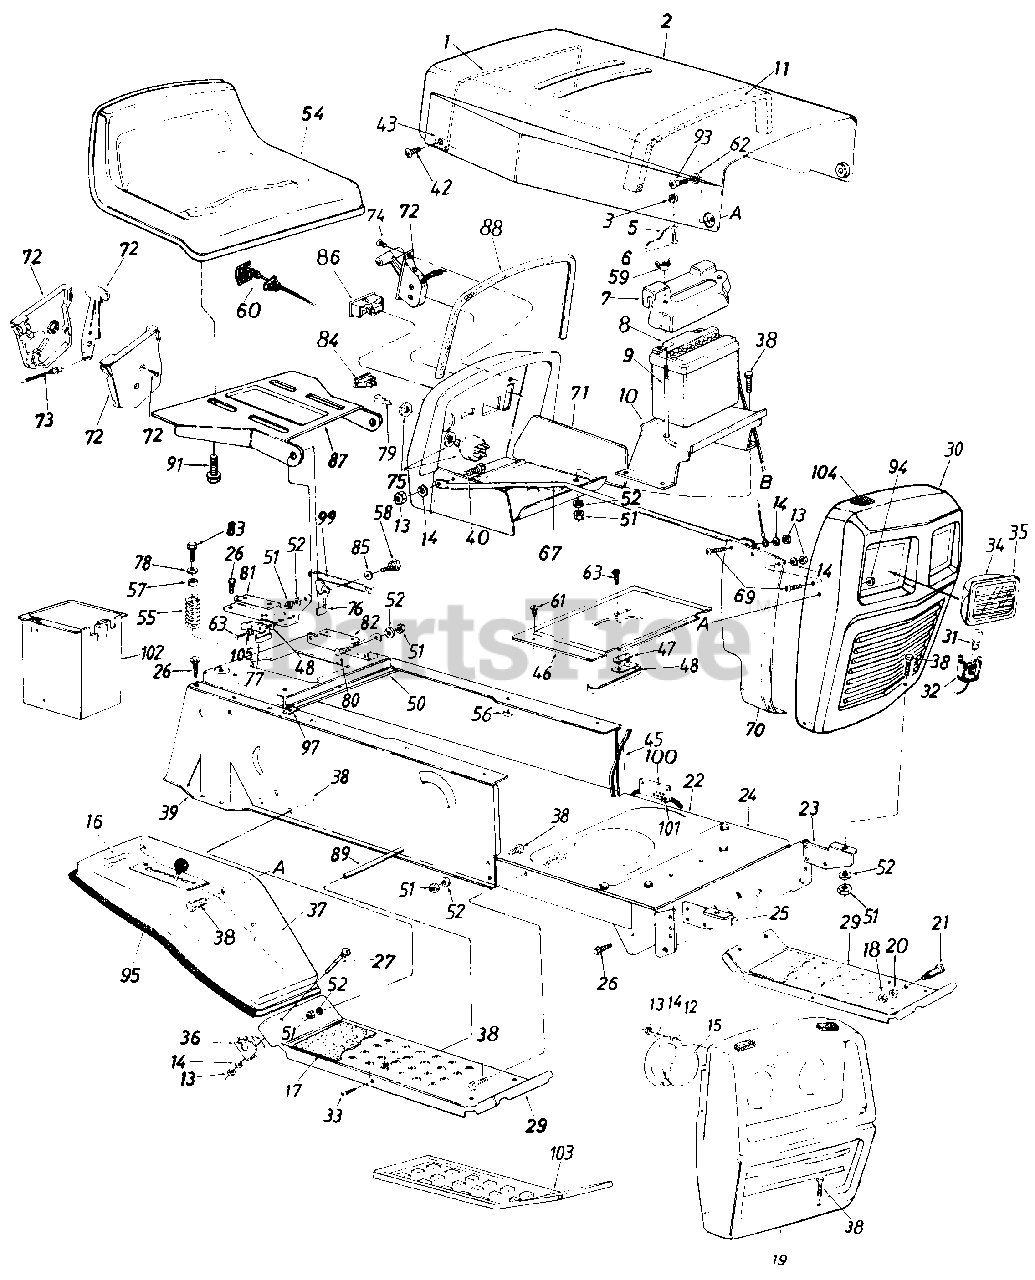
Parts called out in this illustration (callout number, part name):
1	Hood Spring
5	Hood Stop 7" Lg.
6	Pop Rivet .188" Dia.
7	Battery Cover
8	12 Volt Battery
9	Battery Hold Down Rod
10	Battery Bracket
11	PVC Foam-Strip
12	Headlight Retainer
13	Hex Nut 1/4-20 Thd.*
14	L-Wash. 1/4" I.D
15	Headlight
16	Hex Wash. Hd. Tap Scr. 1/4 x 3/8" Lg.
17	Foot Pad
18	Hex Nut 3/8-16 Thd.*
21	Shld. Bolt .50" Dia. x .84
22	Lower Frame
23	Grille Mount Brkt.
24	Front Pivot Brkt.
25	Grille Mount Brkt.
26	Hex Wash. Hd. AB-Tap Scr. 5/16 x .75" Lg.
27	Carr. Bolt 1/4-20 x 2.00" Lg.
29	Running Board
32	Twist Lock-Lamp Sockett
33	Truss Mach. Scr. 5/16-18 x .75" Lg.
34	Headlight Housing
35	Lens
36	Fender Clamp
37	Fender
39	R.H. Side Frame
40	Hex Bolt '/4-20 x .62" Lg.
42	Self-Tap Scr. .5" Lg.
43	Hood Spring Retainer
45	L.H. Side Frame
46	Shift Cover
47	Reverse Safety Switch
48	Insulator Nut Plate
50	Hitch Plate
51	Hex Nut 5/16-18 Thd.
52	L-Wash. 5/16" I.D.*
54	Seat Ass'y.
55	Compression Spring
56	Ext. L-Wash. 5/16" I.D.
57	Bushing
58	Shld. Bolt .437" Dia. x .268"
59	Wing Nut 1/4-20 Thd.-Plastic
60	Choke Control 44.0" Lg.
61	Truss Mach. Tap Scr. #10 x .50" Lg.
62	Washer .39" I.D. x .62" O.D.
63	Hex Wash. Hd. AB-Tap Scr. #8 x .50
67	Grille Support Rod-R.H
70	R.H.-Grille Side Panel
73	Throttle Control Wire-35"
74	Truss Mach. AB-Tap Scr. #10 x .5" Lg.
75	Ignition Switch
76	Seat Lift Bracket
77	Spring Switch
78	Fl-Wash..344" I.D.
79	Ignition Key
80	Shld. Bolt .437" Dia. x .162"
81	Seat Pivot Brkt. Support-R.H.
82	Seat Pivot Brkt. Support-L.H.
83	Hex Hd. Tap Scr. 5/16-18 x 1 " Lg.
84	Light Switch
85	Spr.-Wash. .445" I.D. x .75" O.D.
86	Ammeter
87	Seat Pivot Bracket
88	Molding Strip 27" Lg.
89	Running Board Rod
91	Hex Wash. Hd. Tap Scr. 3/8-16 x .75" Lg.
93	Shld. Bolt .375 Dia. x .125
94	L-Nut 1/4-28 Thd.
95	Trim Strip 31.0" Lg.
97	Speed Nut #10Z
99	Extension Spring 5.31" Lg.
100	Brake Cable Bracket
101	Cable Tie
102	Utility Box
103	Foot Pad-L.H.
104	Foam Strip 3/8 x 1-1/8 x 1-1/2
105	Fiber Washer
